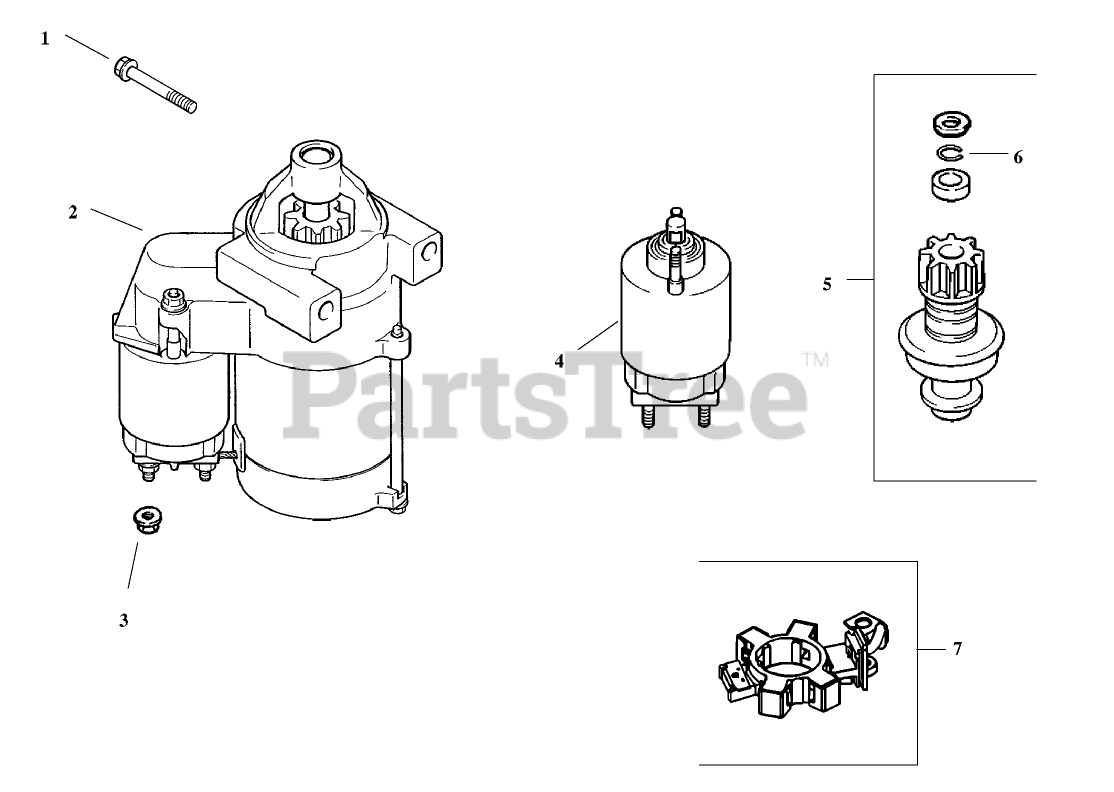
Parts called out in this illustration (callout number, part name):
1	SCREW-FLG (M8X1.25X80)
2	Starter, solenoid shift (Includes 3-7)
3	NUT-FLANGE (M8X1.25)
4	Solenoid Kit
5	Kit, drive (Includes 6)
6	RING-RETAINING
7	BRUSH HOLDER KIT
